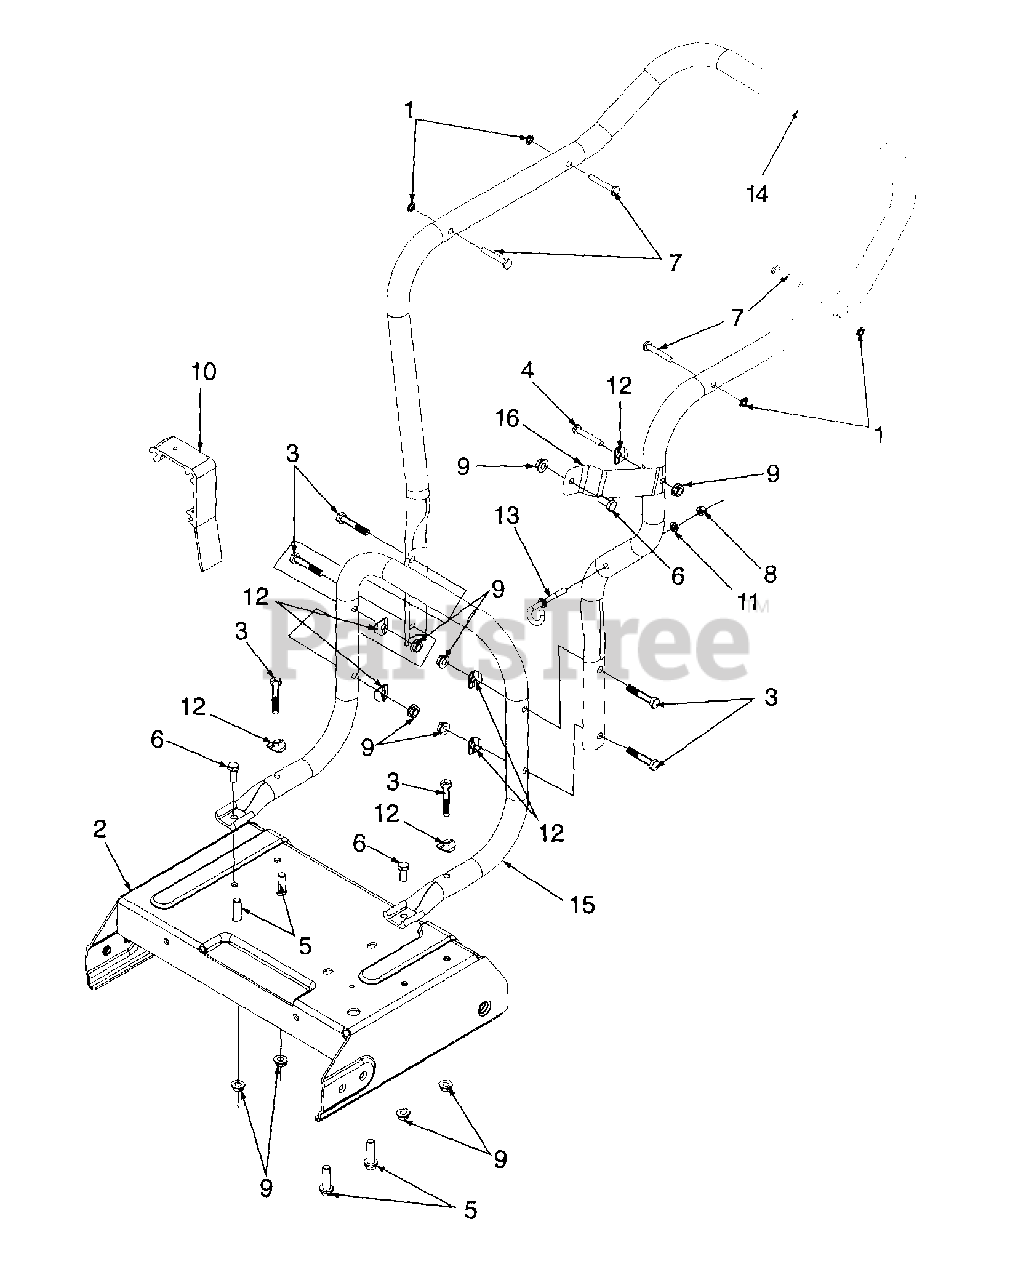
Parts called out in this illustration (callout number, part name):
1	Nut, Push
2	Frame Assembly
3	Screw, Hex Cap, 5/16-18 x 1.75
4	Screw, Hex Cap, 5/16-18 x 1.50
5	Screw, Hex Wash. Hd. Tapp, 3/8-16 x 1.25
6	Screw, Hex Cap, 5/16-18 x .75
7	Pin, Stud, 250 x 1.75
8	Nut Hex, 1/4-28
9	Nut, Hex Flange Lock, 5/16-18
10	Adapter, Mounting
11	Washer, Lock, 1/4
12	Washer, Saddle, .32 ID x .93 OD
13	Bolt, Eye
14	Handle, Upper
15	Handle, Lower
16	Bracket, Chute Stabilizing
